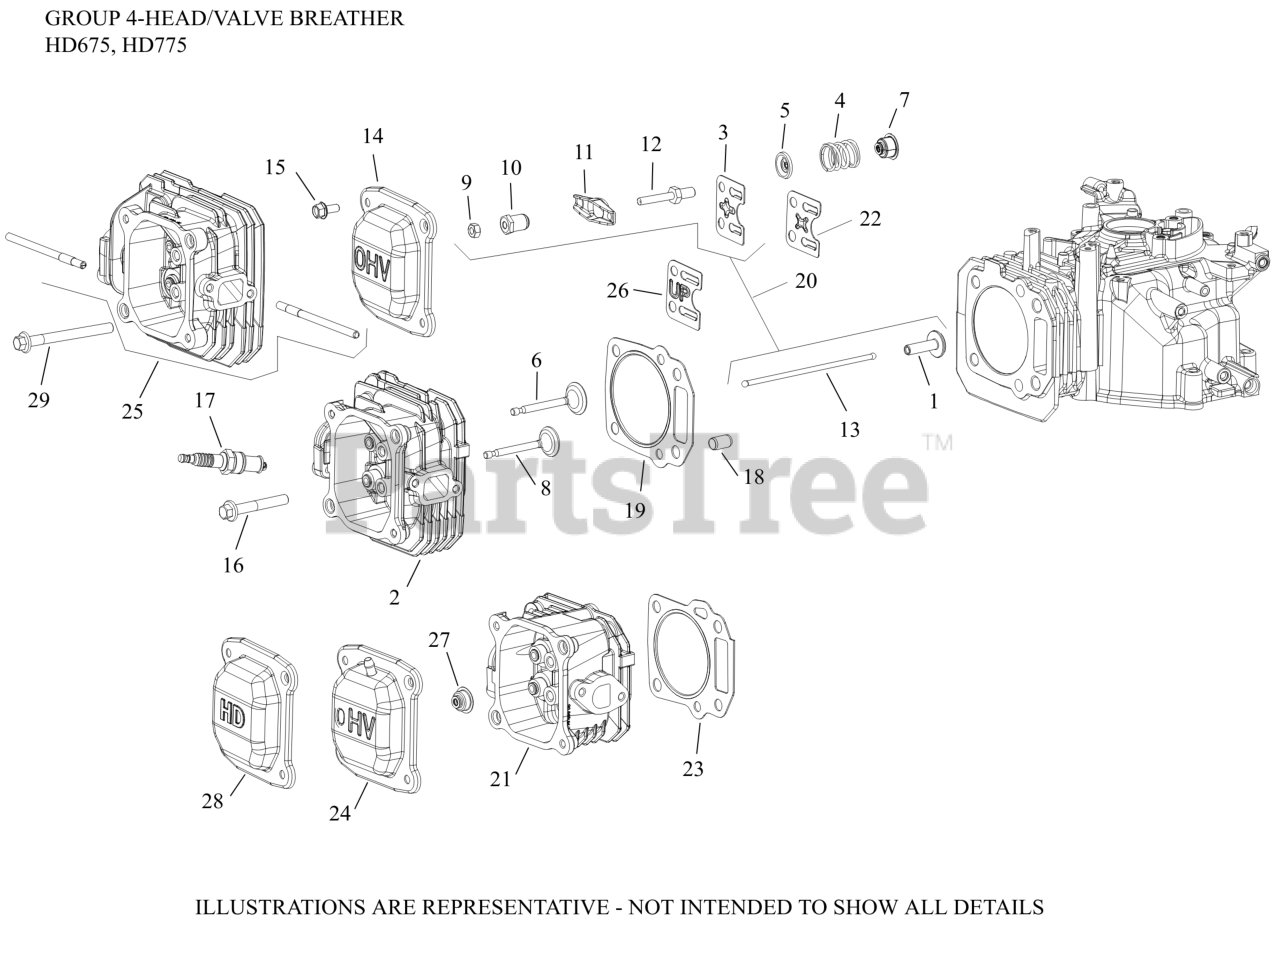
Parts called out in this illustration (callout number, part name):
1	LIFTER, VALVE
2	HEAD, CYLINDER
3	PLATE, PUSHROD GUIDE
4	SPRING, VALVE
5	RETAINER, VALVE SPRING
6	VALVE, INTAKE
7	SEAL, VALVE STEM
8	VALVE, EXHAUST
9	NUT, HEX JAM
10	PIVOT, ROCKER ARM
11	ARM, ROCKER
12	STUD, ROCKER ARM
13	ROD, PUSH
14	COVER, VALVE
16	SCREW, HEX FLANGE M8
17	PLUG, SPARK 12MM RFI
18	DOWEL, CYLINDER HEAD-(#1438013S)
19	KIT, HEAD GASKET-USE 14 841 34-S (XT)
20	KIT, VALVE TRAIN
